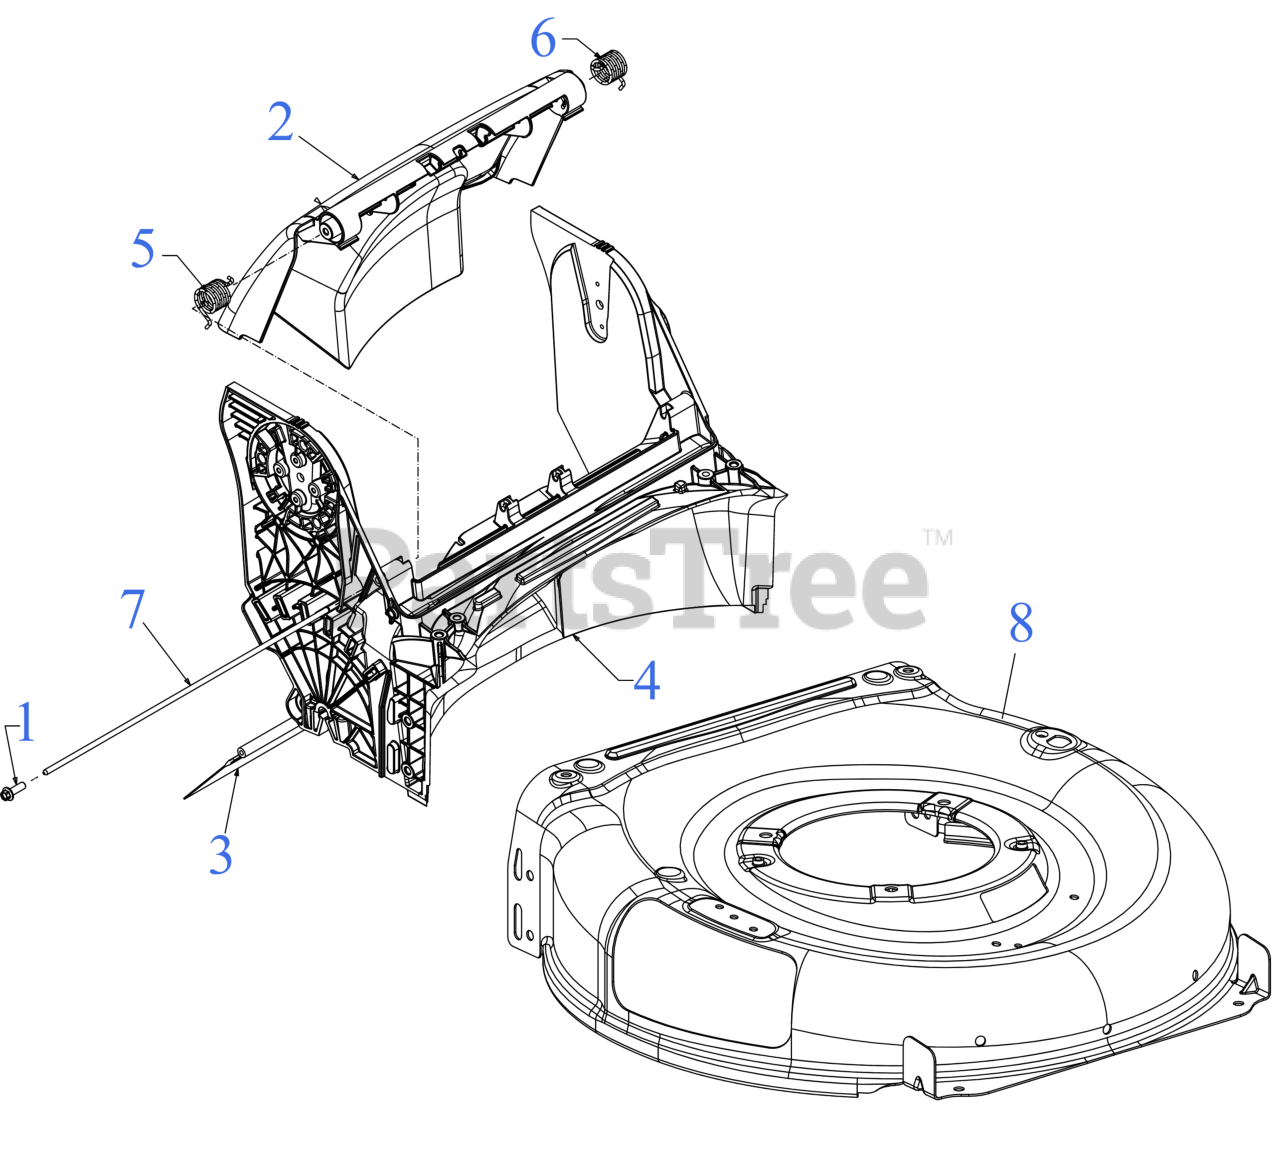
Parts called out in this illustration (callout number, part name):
1	SCREW 1/4 x .750
2	BFL ASM:RR:VERTSTRG
3	TRAILSHIELD
4	BFL ASM:RR:VERTSTRG
5	TORSION SPRING (RH)
6	TORSION SPRING (LH)
7	REAR DOOR PIVOT ROD
